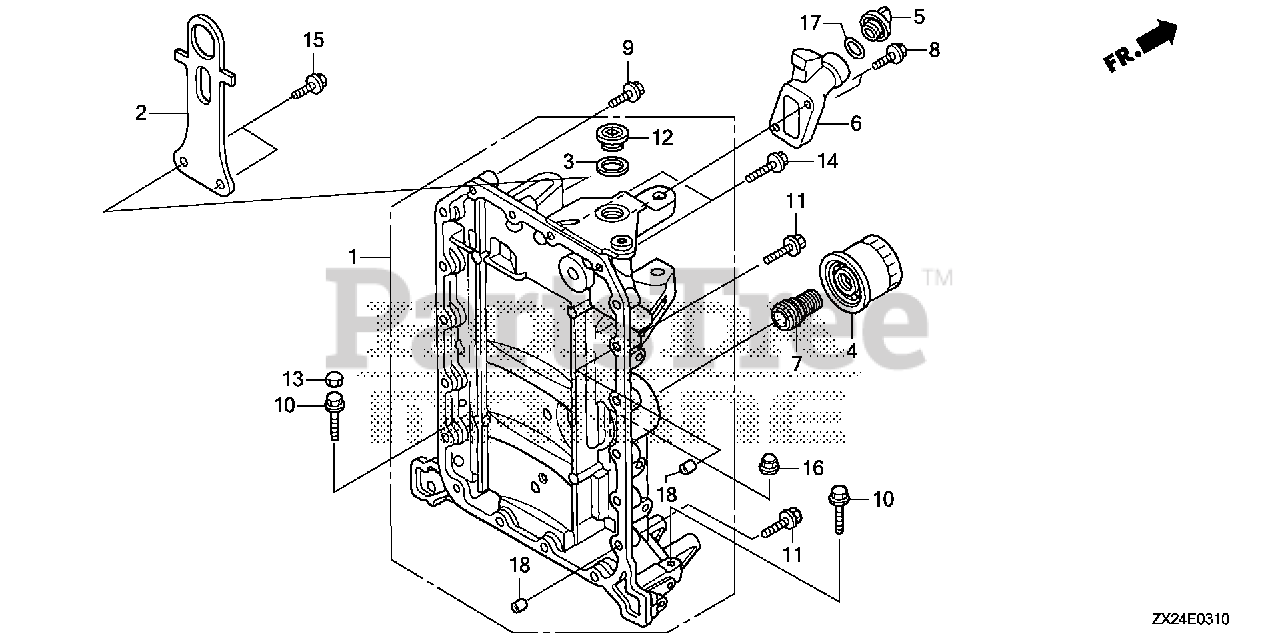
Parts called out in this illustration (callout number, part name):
1	CRANKCASE
2	HANGER, ENGINE
3	WASHER, SEALING (22MM)
4	FILTER, OIL (FILTECH TOYO ROKI) (SOLD IN MULTIPLES OF 30)
4	FILTER, OIL (FILTECH TOYO ROKI) (SOLD INDIVIDUALLY)
5	CAP, OIL (YELLOW)
6	EXTENSION, OIL FILLER
7	HOLDER, OIL FILTER
8	BOLT, FLANGE (6X22)
9	BOLT, FLANGE (6X32)
10	BOLT, FLANGE (10X55)
11	BOLT, FLANGE (6X37)
12	BOLT, SEALING (22MM)
13	CAP, BOLT (10MM)
14	BOLT, FLANGE (6X55)
15	BOLT, FLANGE (8X25)
16	NUT, FLANGE CAP (10MM)
17	O-RING (26X2.7)
18	PIN, DOWEL (8X14)
